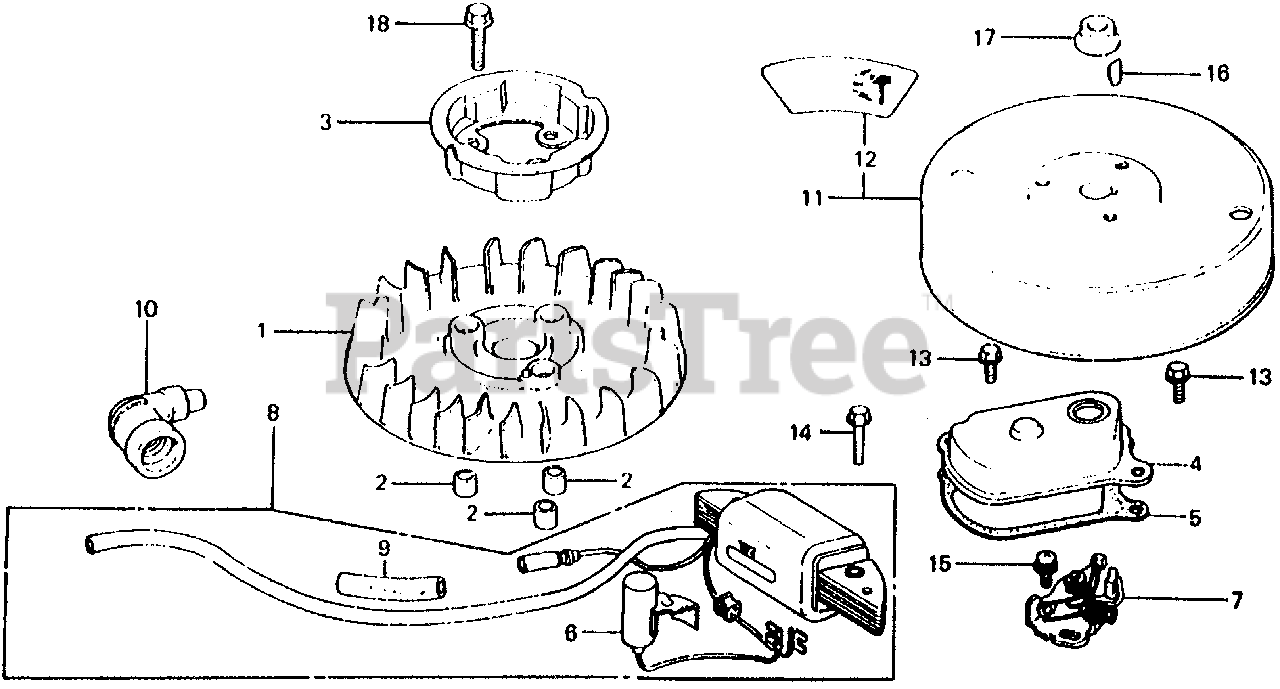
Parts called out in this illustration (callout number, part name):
1	FAN, COOLING
2	COLLAR, FAN
3	PULLEY, STARTER
4	COVER, POINTS
5	GASKET, BREAKER COVER
6	CONDENSER (NOT AVAILABLE)
7	POINTS ASSY.
8	COIL ASSY., IGNITION (NOT AVAILABLE)
9	TUBE, IGNITION RUBBER
10	CAP ASSY., NOISE SUPPRESSOR
12	MARK, FLYWHEEL CAUTION
13	BOLT, FLANGE (5X10)
14	BOLT, FLANGE (5X25)
15	SCREW-WASHER (5X12)
16	KEY, WOODRUFF (3MM)
17	NUT, FLANGE (12MM)
18	BOLT, FLANGE (6X22)
